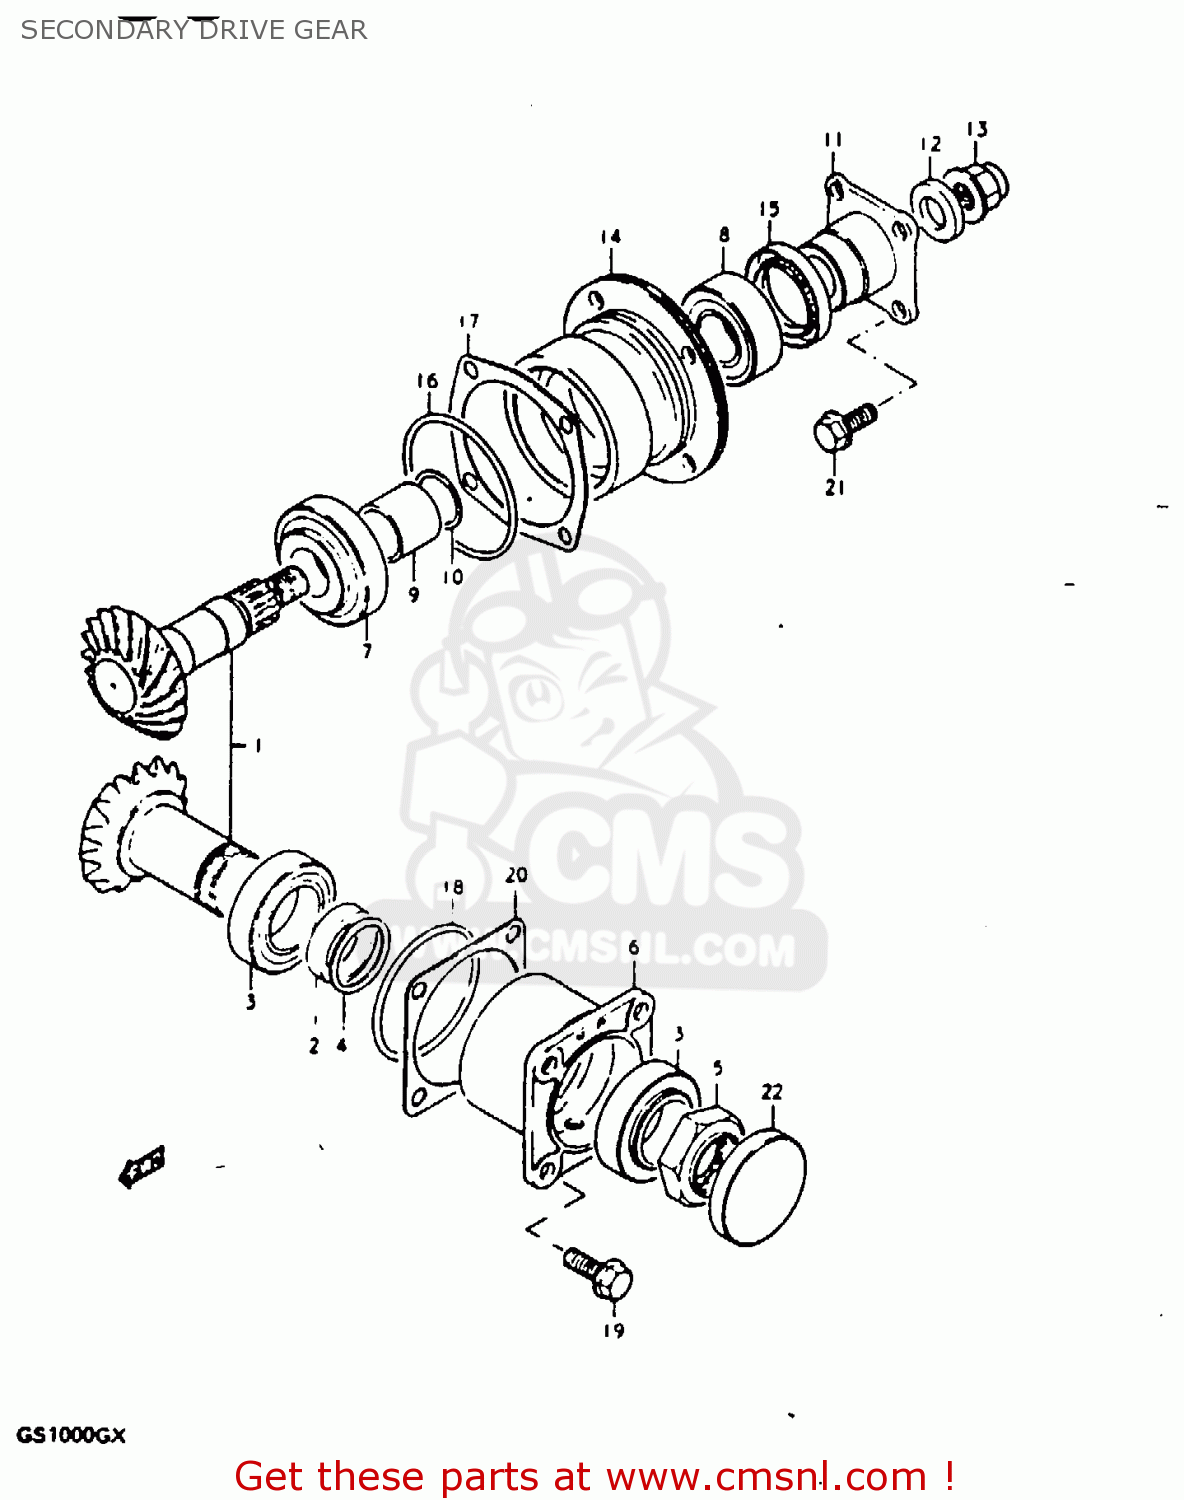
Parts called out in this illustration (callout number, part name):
1	SECONDARY GEAR SET
2	SPACER (32.4X38X12.5)
3	BEARING(32X58X17)
4	SHIM(32X38X2)
5	NUT
6	HOUSING,SECONDARY DRIVE
7	TAPER,ROLLER BEARING
8	BEARING
9	SPACER (25.2X30X40)
10	SHIM (25X30X2
11	FLANGE,UNIVERSAL JOINT
12	WASHER(14X29X4)
13	NUT
14	HOUSING,SECONDARY DRIVE
15	SEAL,OIL(35X52X9)
16	O RING(D:3.1,ID:69.4)
17	SHIM,DRIVEN GEAR HOUSING
18	O RING(D:2.4,ID:62.6)
19	BOLT
20	SHIM,SECONDARY DRIVE
21	BOLT
22	PLUG
